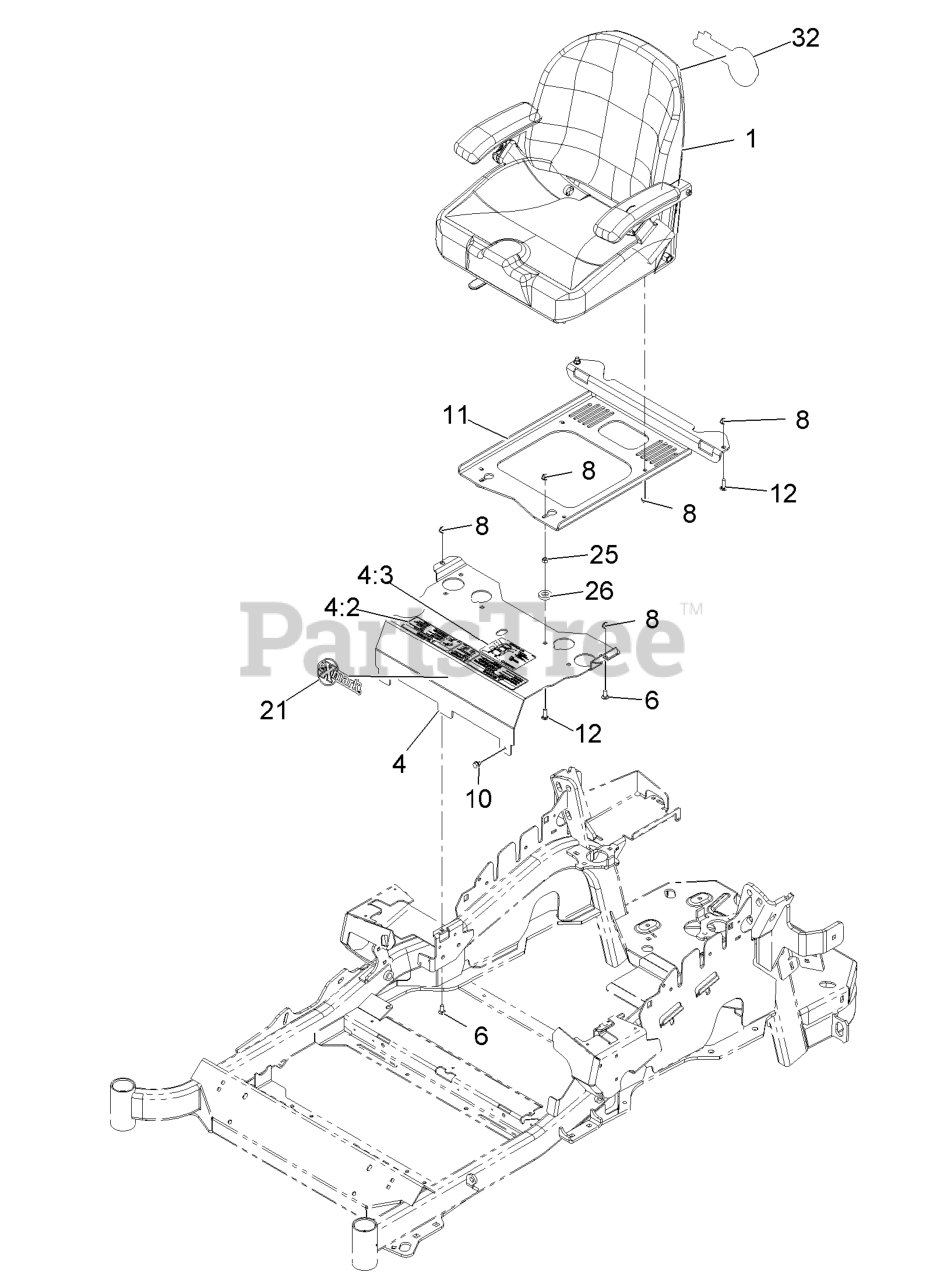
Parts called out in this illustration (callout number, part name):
4	MOUNT-SEAT
4:2	DECAL-CONSOLE
4:3	DECAL-SERVICE AID
6	SCREW-CARR
8	NUT-HF, NI
11	PLATE-SUPPORT, SEAT
12	SCREW-CARR
25	NUT-HEX
32	DECAL,EXMARK LOGO
